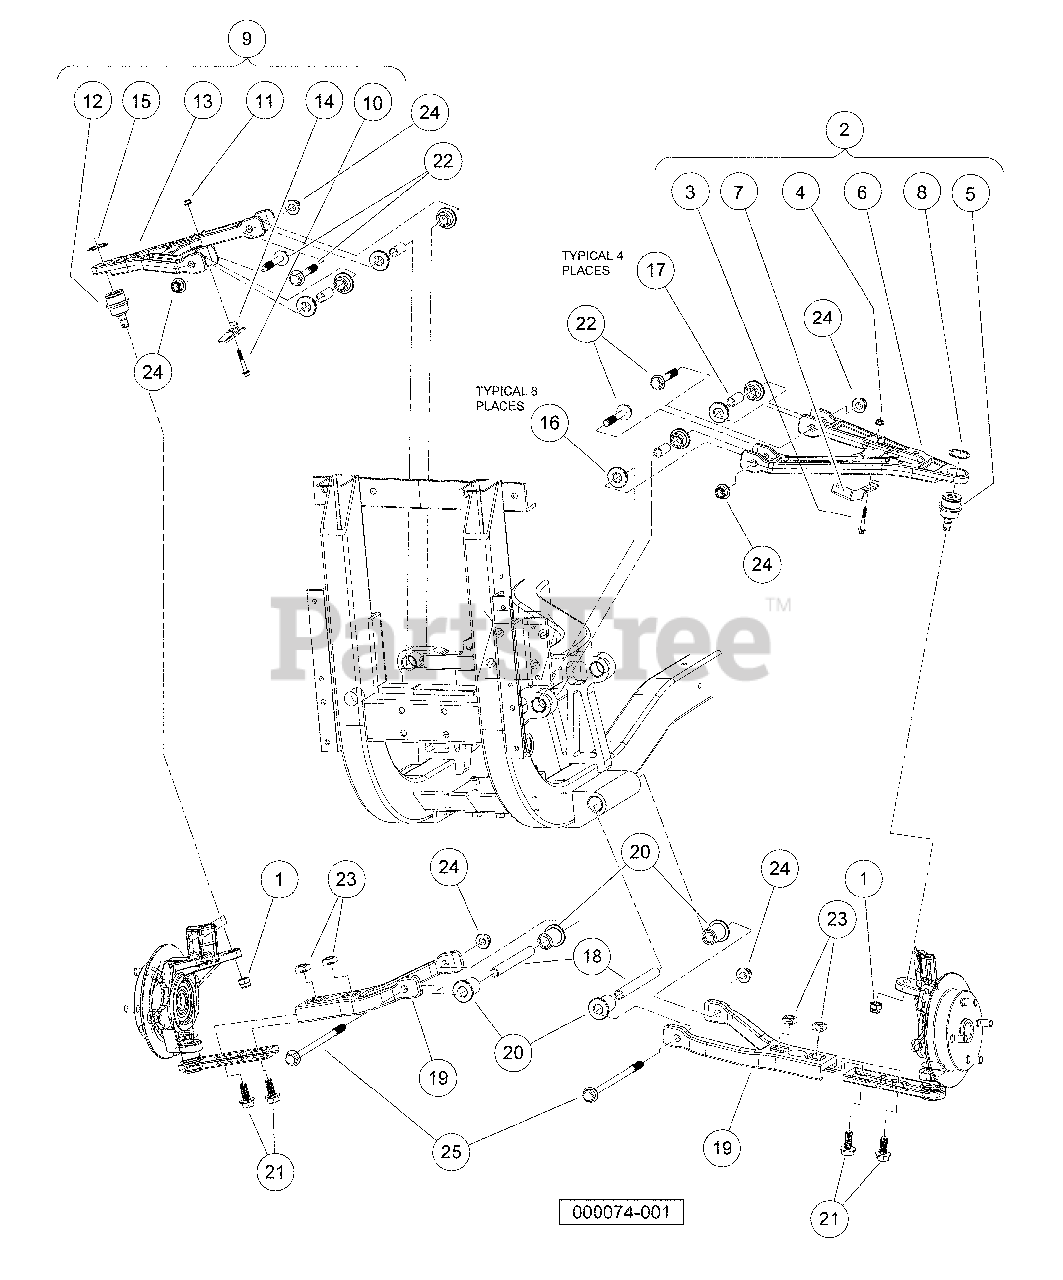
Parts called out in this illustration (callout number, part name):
1	Locknut, M12-1.25 Nylon
2	Sub-assembly, A-Arm, Upper, LH
3	Bolt, Flanged Head, M6x1.0x40
4	Nut-m6x1.0 Flng All Mtl Lock
5	Joint, Ball
6	A-Arm, Upper, Left
7	Bracket, Brake Line, Left
8	Ring, Retaining, Ext, 1-1/4"
9	Sub-assembly, A-Arm, Upper, RH
10	Bolt, Flanged Head, M6x1.0x40
11	Nut-m6x1.0 Flng All Mtl Lock
12	Joint, Ball
13	A-Arm, Upper, Right
14	Bracket, Brake Line, Right
15	Ring, Retaining, Ext, 1-1/4"
16	Bushing, A-Arm
17	Sleeve, Upper
18	Sleeve, Lower
19	Arm, Lower
20	Bushing, Lower Arm
21	Bolt, Flange Head, M12x 1.75x 30 with Loctite
22	Bolt, Flange Head, M12 X 1.75 X 70
23	Nut, Square, M12x 1.75
24	Nut Flg, M12x1.75, Nylon Gr 10
25	Bolt Flg, M12 X 1.75 X 200 10
